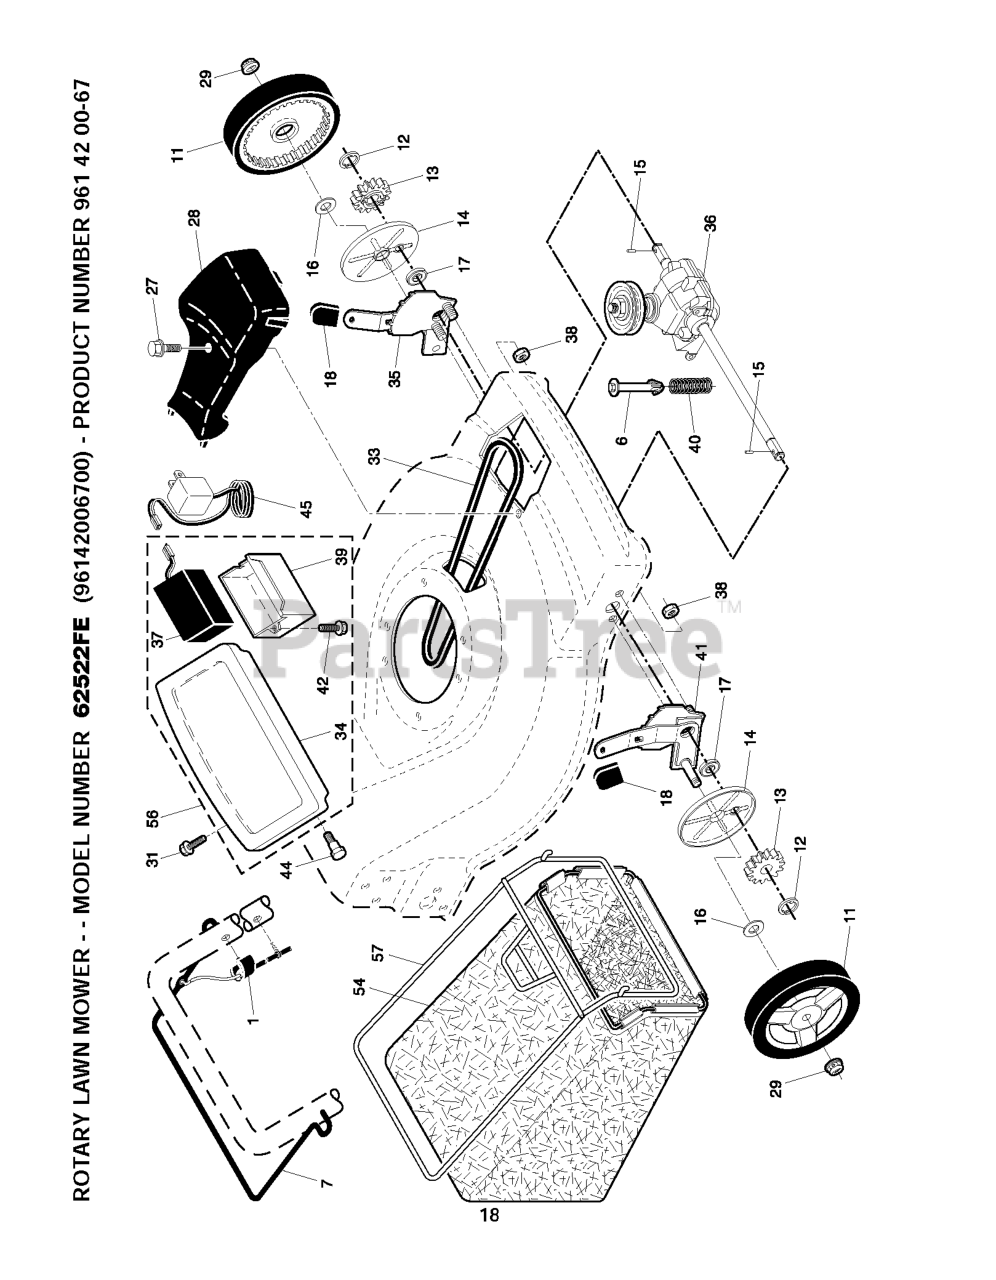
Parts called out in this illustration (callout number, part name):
1	CONTROL.DRIVE.S/SPEED.FWGD
6	SPRING RETAINER
7	BAIL.CONT.DR.S/S.ROUND.ORG
11	WHEEL.8X1.75.H3SPK.RAD3.GY.BU3
12	E-RING 7/16 RE
13	PINION.14.TEETH.FGD
14	COVER.DUST.WHEEL
15	PAWL, DRIVE
16	WASHER FLUT
17	BEARING
18	SELECTOR KNOB
27	SCREW, HEX HD TAPPING #10-24 1
28	BOLT SHOULDER 3/8 -16X1
29	NUT.HEX.FLANGE.3/8-16.LO(3 2)
31	SCREW.PAN.HEAD.#10
33	BELT THERM .32
34	PANEL.TRIM.21.FWGD.ES
35	RP KIT, WHEEL ADJUSTER, LH
36	TRANSMISSION.22.FGD/W/PULLEY
37	BATTERY WITH AMP CONECTOR AGM
38	LOCKNUT.NYLOC.1/4-20
39	BOX.BATTERY.TRIM
40	SPRING.EXTENSION
41	KIT, WHEEL ADJUSTER, RH
42	SCREW.HWH.13-16X.50
44	SCREW.SHOULDER.HH.10X.281X.6
45	RP CHARGER.BATTERY
54	WASHER.FLAT.1/2
56	PANEL.ASM.TRIM/BATTERY.BOX
57	FRAME.GBAG.22.EZ.EMPTY.SC
